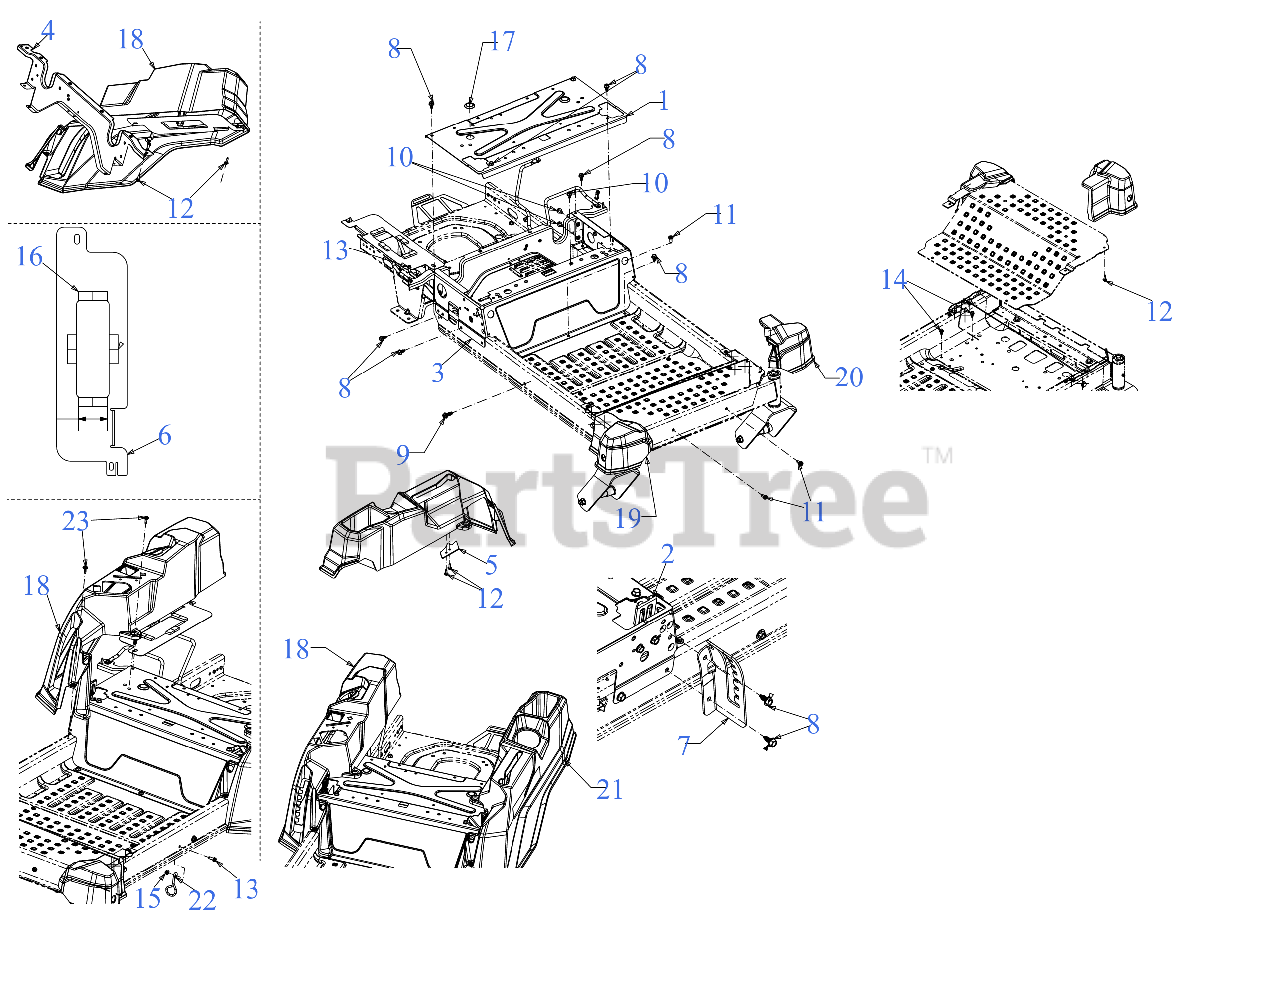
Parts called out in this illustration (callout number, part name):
7	HEIGHT INDEX BRACKET
8	SCREW 5/16-18 x .750
9	SCREW 3/8-16 x 1
10	SCREW 5/16-18 x .500
11	SCREW 5/16-18 X.75
12	SCREW 1/4-10 x .750
13	SCREW 1/4-20 x .750
14	SCREW 1/4-20X.625
15	FLANGE LOCK NUT
16	FOAM TAPE 12"LG FROM BULK
18	CONSOLE (RH)
19	AXLE COVER (RH) W/HEADLIGHT
20	AXLE COVER (LH) W/HEADLIGHT
21	MANUAL PTO CONSOLE (LH)
22	CABLE GUIDE
23	SHOULDER SCREW M6-1 .368 X.115
